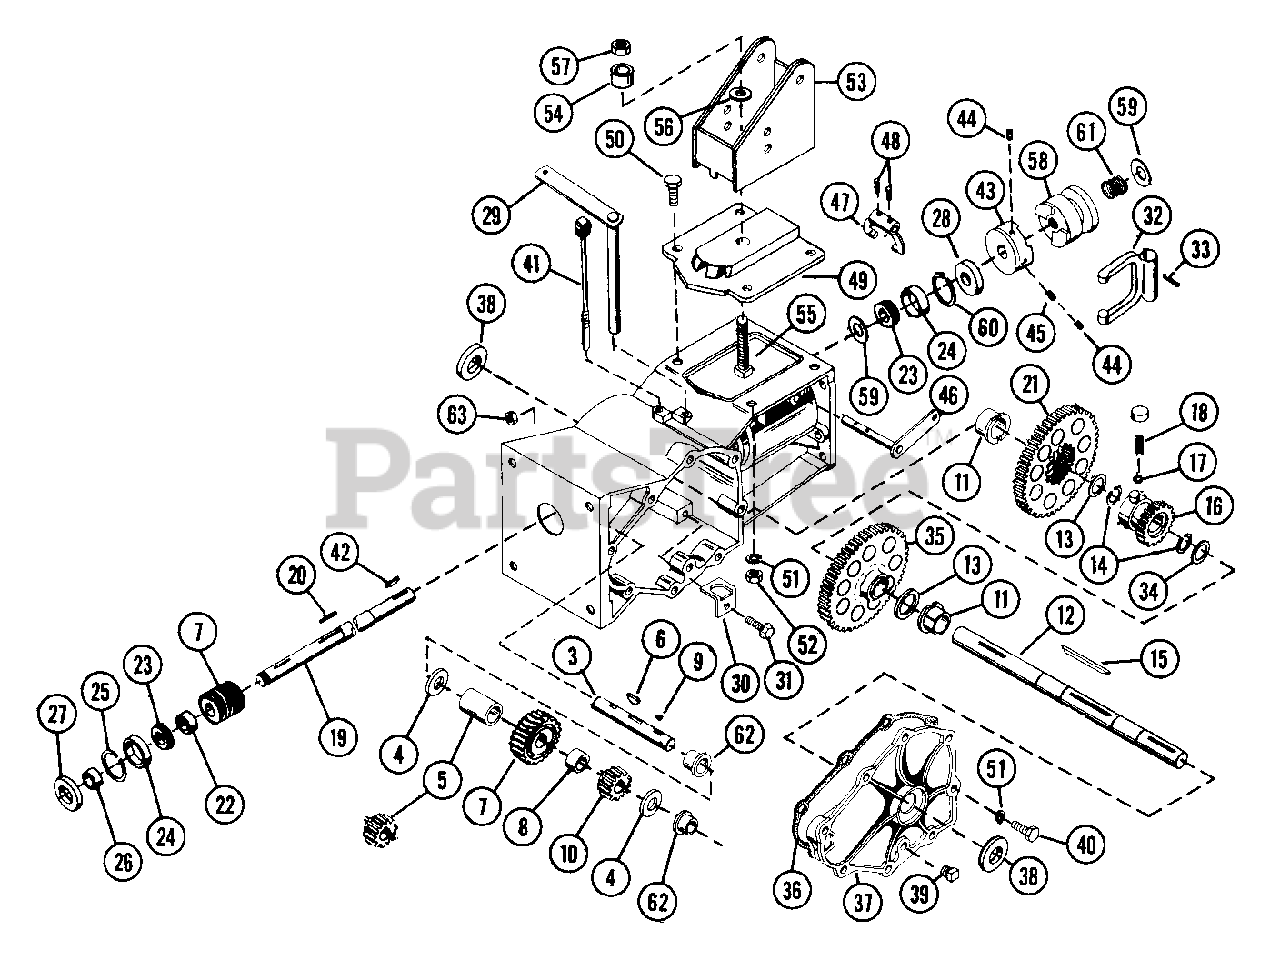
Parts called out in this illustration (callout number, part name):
1	TILLER GEARCASE ASSEMBLY
1	TRANSMISSION GEARCASE ASSEMBLY
2	TRANSMISSION HOUSING
3	PINION SHAFT
3	SHAFT, PINION
4	WSHR-HDND-THRST .758X1.23X.031
5	SPACER 1.13 X .75 X 1.64
5	HIGH PINION
6	KEY-WDRF .25X.687X.375
7	WORM AND WORM GEAR
8	SPACER 1.25 X .75 X .75
9	KEY-WDRF .188X.75X.313 SAE 9
10	LOW PINION
11	BSHG-FLG 1.000X1.25X1.000X1.50
12	AXLE SHAFT
13	WSHR-HRD-THRS 1.007X1.542X.062
14	RG-RTNG-EXT 1.00X.078
15	KEY-FTHR .25X2.75X.25 SAE1035
16	CLUTCH HUB
17	STEEL BALL
18	SG-COMP .047X.31X.593 WLD11
19	WORM SHAFT
20	KEY-SQ .188X1.0X.188 SAE 8630
21	HIGH GEAR
22	BSHG, SPCR .755X1.12X.50 PM
23	BRG-CONE .750X.61
24	BRG-CUP 1.781X.475
25	SNAP RING KIT
26	SPACER BUSHING .99 X .75 X .50
27	SEAL 1.000X1.785X.250
28	SEAL .750X1.781X.250
29	HIGH-LOW SHIFT LEVER
30	RETAINER CLIP
31	SCR-FLG-WHZ 10-24X.75 PL
32	SHIFT YOKE
33	PIN-ROLL .250X1.00
35	LOW GEAR
37	TRANSMISSION COVER
38	SEAL 1.000X1.785X.250
39	PIPE PLUG
40	BLT-HEX .31-18X1.00 PL GR 2
41	DIP STICK
42	KEY-FTHR .188X1.25X.187 SAE
43	TILLER DRIVING JAW
44	SCR-SET .32-18X.38 SKHCUPNL OH
45	SCR-SET .32-18X.50 SKHHOP OH
46	TINE ENGAGING FORK SHAFT
47	CLUTCH FORK
48	PIN-ROLL .188X1.00
49	PIVOT CAP
50	BLT-HEX .31-18X1.00 PL GR 2
51	WSHR-LK .312X.097 PL HVY
52	NUT-SPEED FLAT 10A
53	HANDLE BRACKET
53	HANDLEBAR BRACKET
54	ROLLER
55	SWIVEL BOLT
56	WSHR-FL-STL .511X1.441X.125 PL
57	NUT-LK-CTR .50-13
58	TILLER JAW CLUTCH
59	WSHR-FL-STL .755X1.375X.125
60	RG-RTNG-INT 1.781X.052
61	SG-COMP .080X.97X2.18 WLD14
62	BSHG-FLG .750X1.000X.750X1.250
63	NUT-HEX .375-16
